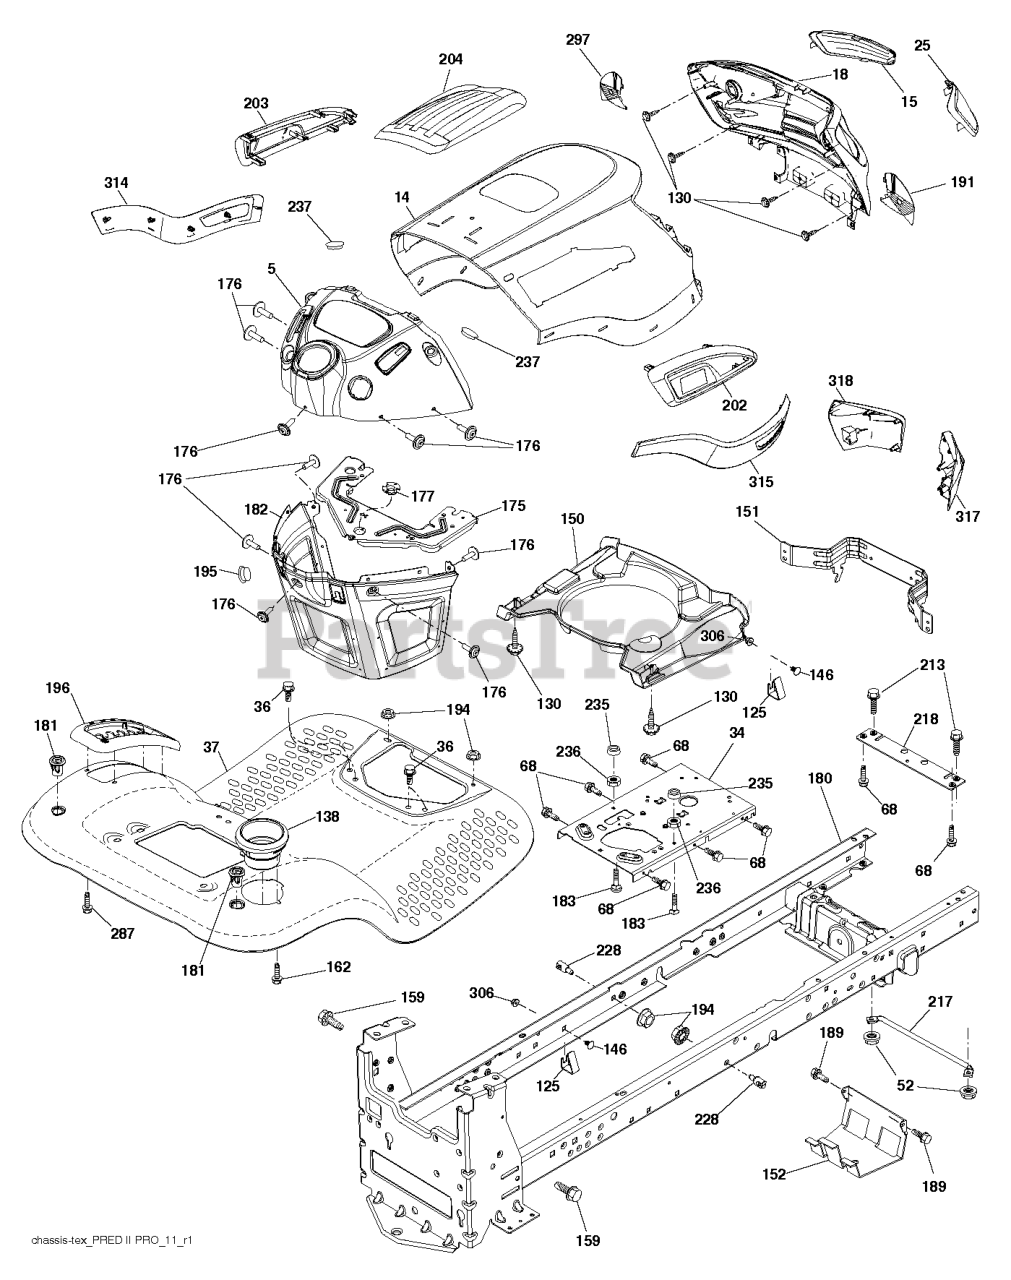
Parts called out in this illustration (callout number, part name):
5	DASH.YT.PRED.SQG.EL.W/C.BLK
14	HOOD HOOD.GRILL.PREDII.YT/GT.Y
15	LENS.LH.PRED II.YT.CLR.SVC
18	GRILLE.SUBASM.PREDII.GT.REDMAX
25	LENS.RH.PRED II.YT.CLR.SVC
34	PLATE.ENGINE.WELDED.CHASSIS
36	SCREW 5/16"
37	FENDER.TLT.PDLCONTROL.WCUPX672
52	Hardware
125	CLIP.FUEL.LINE
138	CUPHOLDER.TL.TEX.BLACK
146	BOLT.RDHD.SHT.SQNK.3/8-16X5/8
150	PREDATOR.YT.GT.HOOD.AIR DUCT
151	BRACKET.PIVOT.PREDATOR
152	SHIELD.BROWNING.W/TEX
159	SCREW, 3/8-16X3/4
175	PLATE.PNT.CROSSMEMBER.HUSQ/PRE
176	SCREW.#10-24X5/8.RN.QU
177	BUSHING STEERING
180	CHASSIS
181	BUSHING.MNT.FEND.CRGO.
182	DASH.LOWER.COMMON.12V.ADAPTOR
189	SCREW
191	INSERT INSERT.REFLECTIVE.RH
194	GSPW Nuts
195	PLUG.HOLE.DASH.LOWER.12V.BLK
196	CONSOLE.ASM.DECKLFT.BL/RBT.TLT
202	VENT SIDE. HOOD. PREDATOR II.
203	VENT SIDE. HOOD. PREDATOR II.
204	VENT ASM.TOP.PRED GT PRO.428
213	SCREW HEXAGON HEAD SCREW 5/16-
217	ROD.PIVOT.HOOD
218	X-PIECE.HOOD.STOP.NON/
228	STUD.FASTNER.W/ANTI-ROTATE
236	NUT.CENTERLOCK.5/16-
237	PLUG.MOUNT.CARGO.BLK
287	SCREW 1/4X20
297	INSERT INSERT.REFLECTIVE.LH
306	NUT LOCK FLG 3/8-16 UNC
317	BUMPER CORNER. PREDATOR II. GT
318	BUMPER CORNER. PREDATOR II. GT
